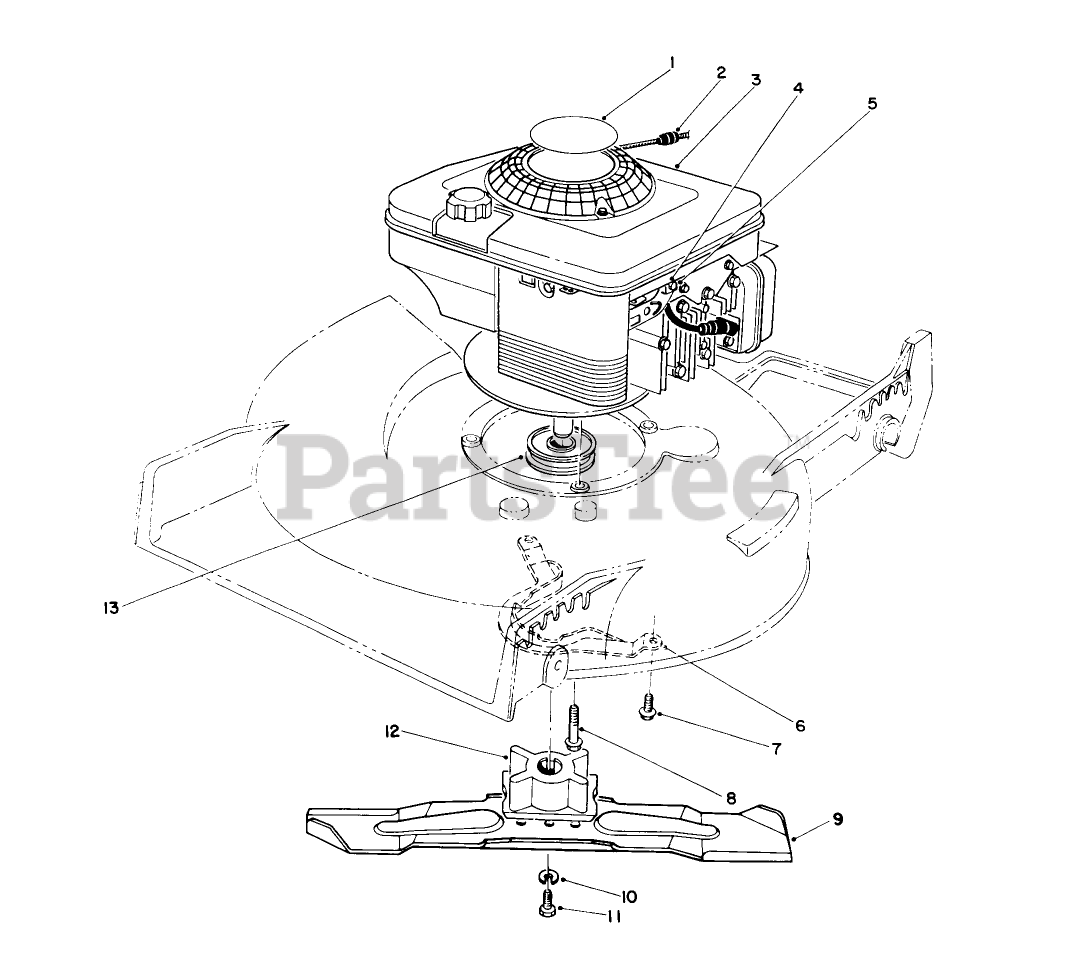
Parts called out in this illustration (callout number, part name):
2	STOP-ROPE
3	Engine
4	CLAMP-CASING
5	CLAMP-CASING
7	SCREW-HWHTF
8	SCREW-HWH
10	WASHER-LOCK
11	SCREW-BLADE
12	BLADE RETAINER
13	PULLEY-DRIVE, ZONE START
